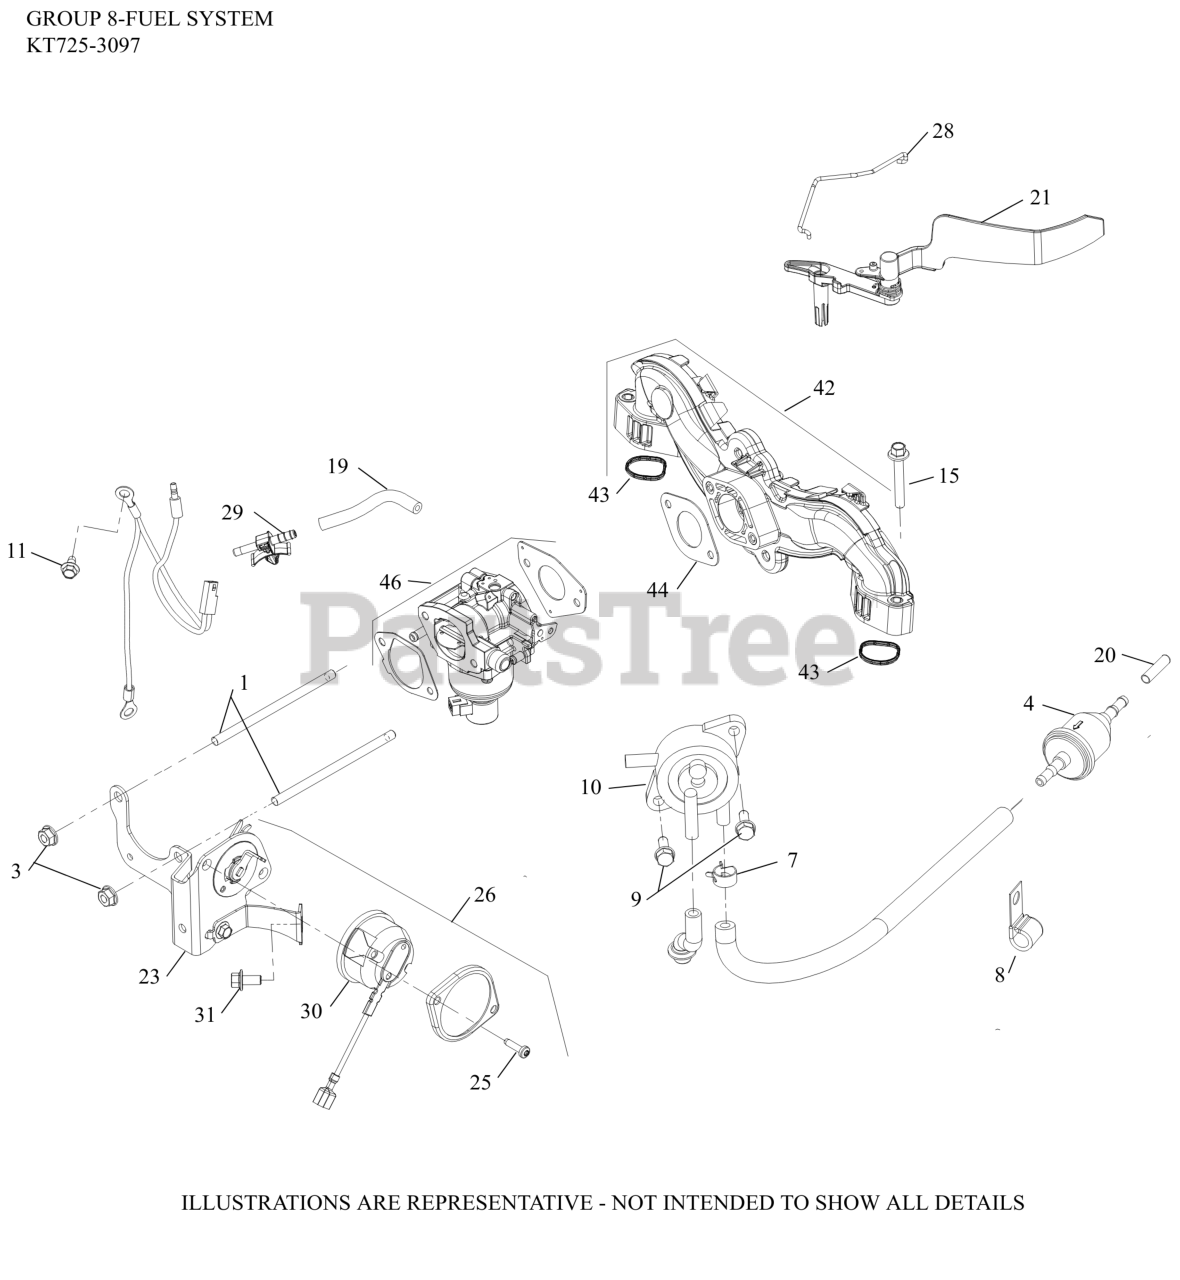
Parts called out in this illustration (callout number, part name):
3	NUT, FLG M6X1.0
4	FILTER,FUEL 51 MICRON (FUEL PUMP)
6	HOSE,LW PERM.FUEL 24.00"-USE 25 111 81-S
7	SPRING CLAMP, HOSE
8	CLIP, CABLE (KM)
9	SCREW, TAP M6X1.7X18
10	PUMP, FUEL (PULSE)-(#2539326S)
11	SCREW, THREAD FORMING
15	SCREW, FLG M6X1.0X40
19	HOSE EVAPORATIVE (WALBRO)
20	CAP, MASKING
21	DEFLECTOR ASSEMBLY, AIR VANE
23	BRACKET ASSY, AUTO-CHOKE (MECH)
25	SCREW, PAN HEAD THREAD FORMING (M4)
26	THERMOSTAT ASSY (CDI) - USE 32 755 27-S
26	THERMOSTAT ASSY(MDI IGN)-USE 32 755 27-S
28	LINKAGE, CHOKE UPLOADER
29	CONNECTOR, EVAPORATIVE
30	KIT, THERMOSTAT, ELECTRIC CHOKE
31	SCREW, FLG M6X1.0X12
42	INTAKE MANIFOLD W/GASKETS
43	O-RING, INTAKE PORT
44	GASKET, CARBURETOR (PIM, CV)
46	KIT,CARB(NIKKI)
NI	KIT, BOWL WITH O-RINGS NIKKI G-TYPE TWIN
NI	KIT, FLOAT AND NEEDLE NIKKI G-TYPE TWIN
NI	KIT,CHOKE REP(SMART/E-CHOKE)-DISC.
NI	KIT, O-RING
NI	KIT, SOLENOID (NIKKI)
NI	KIT, HIGH ALTITUDE 5000 FT.
